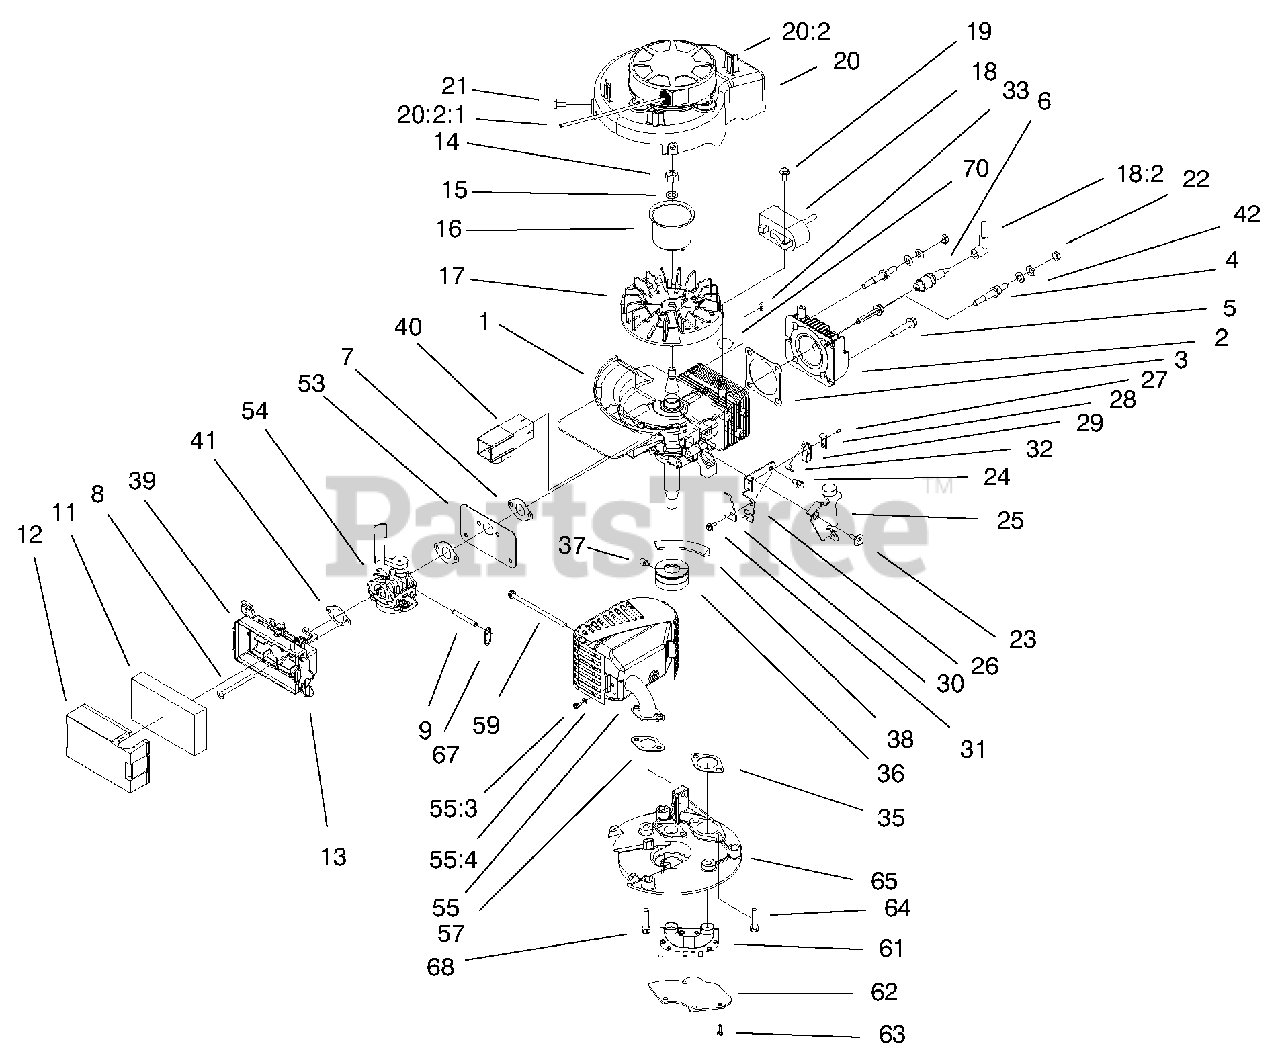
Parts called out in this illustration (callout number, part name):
1	Short Block Ay
2	Head-(Mach)
3	Gasket-Head
5	Bolt-Head
6	Plug-Spark
7	Gasket-Intake
9	Hose-Primer
11	Filter-Air
12	Cover-Air Filter
13	Retainer-Fil.
15	Washer-Lock
16	Cup-Starter
17	Flywheel Machined
18	Ignition-Cd
18:2	Ht Lead&cover
18:2	Cover & Term. Ay
19	Screw-Cd Mtg
20	Shroud-Recoil
20:2	Recoil And Decal ASM
21	Screw-HH
23	Screw-Shoulder
24	Screw-HWH
25	Brake Plate Ay
26	Plate-Brake Mtg
27	Rivet-Plastic
28	Strap-Insulation
29	Strap-Ground
30	Stop-Gr Strap
31	Screw-Special
32	Wire-Lead
35	Gasket-Exhaust
37	Screw-Set
39	Base Ay-(Air Filter)
41	Gasket-Filter
42	Washer-Belleville
53	Shield-Carb.
54	Carb. ASM
55	Muffler And Guard ASM
55:3	Screw-HWH
55:4	Washer-Lock/Int
57	Gasket E
59	Bolt-Console
61	Pipe-Transfer
62	Cover-Muffler
63	Screw-HH
64	Screw-HH
65	Plate-Muffler
67	Hose-Retainer
68	Screw-HH
70	Strap-Tie
